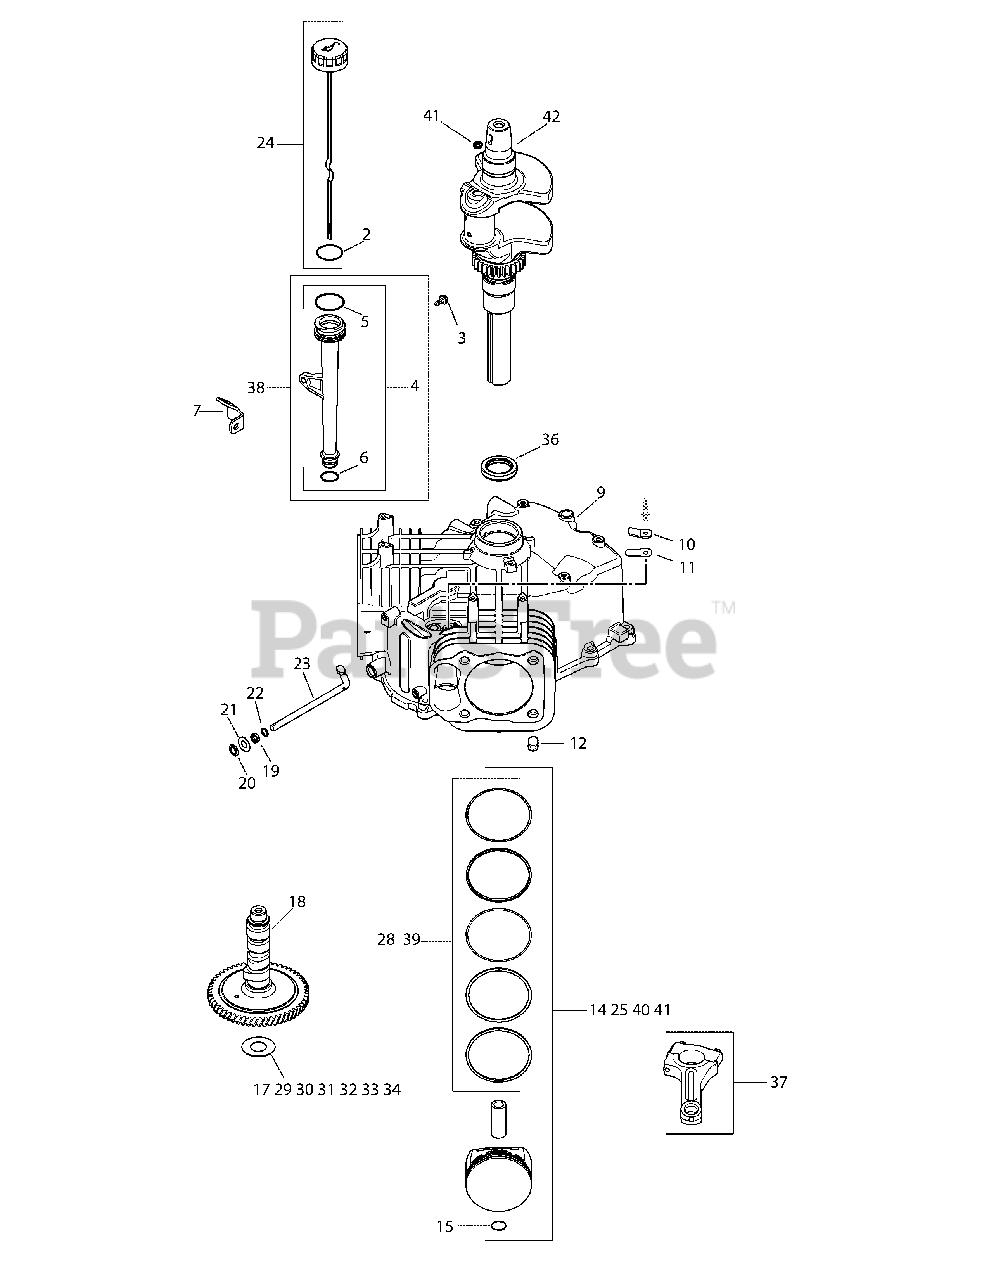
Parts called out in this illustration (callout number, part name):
2	Dipstick Assembly (Includes 2)
3	Flg. Thd. Frm. Screw, M5 X 0.8 X 13
7	Oil Fill Tube Bracket
10	Breather Reed Retainer
11	Breather Reed
14	Piston Kit w/ Ring Set (Inc. 15, 16)
15	Piston Pin Retainer
17	Camshaft Shim (White .028")
18	Camshaft Kit (Inc. KH-25-357-14-S)
19	Governor Cross Shaft Seal
20	Ring Retainer
21	Flat Washer, 9 Mm
22	Flat Washer, 11/32
23	Governor Cross Shaft
24	Dipstick Assembly (Inc. 2)
25	Piston Kit w/ Ring Set (0.25) 83mm
28	Ring Set (.25)
29	Camshaft Shim (Blue .03")
30	Camshaft Shim (Red .032")
31	Camshaft Shim (Yellow .034")
32	Camshaft Shim (Green .036")
33	Camshaft Shim (Gray .038")
34	Camshaft Shim (Black .04")
36	Oil Seal (Helix Lip)
37	Connecting Rod (Std)
38	Tube Assembly (Inc. 4-6)
39	Ring Set (Std)
40	Kit, Piston w/Ring
42	Crankshaft (Includes 2)
